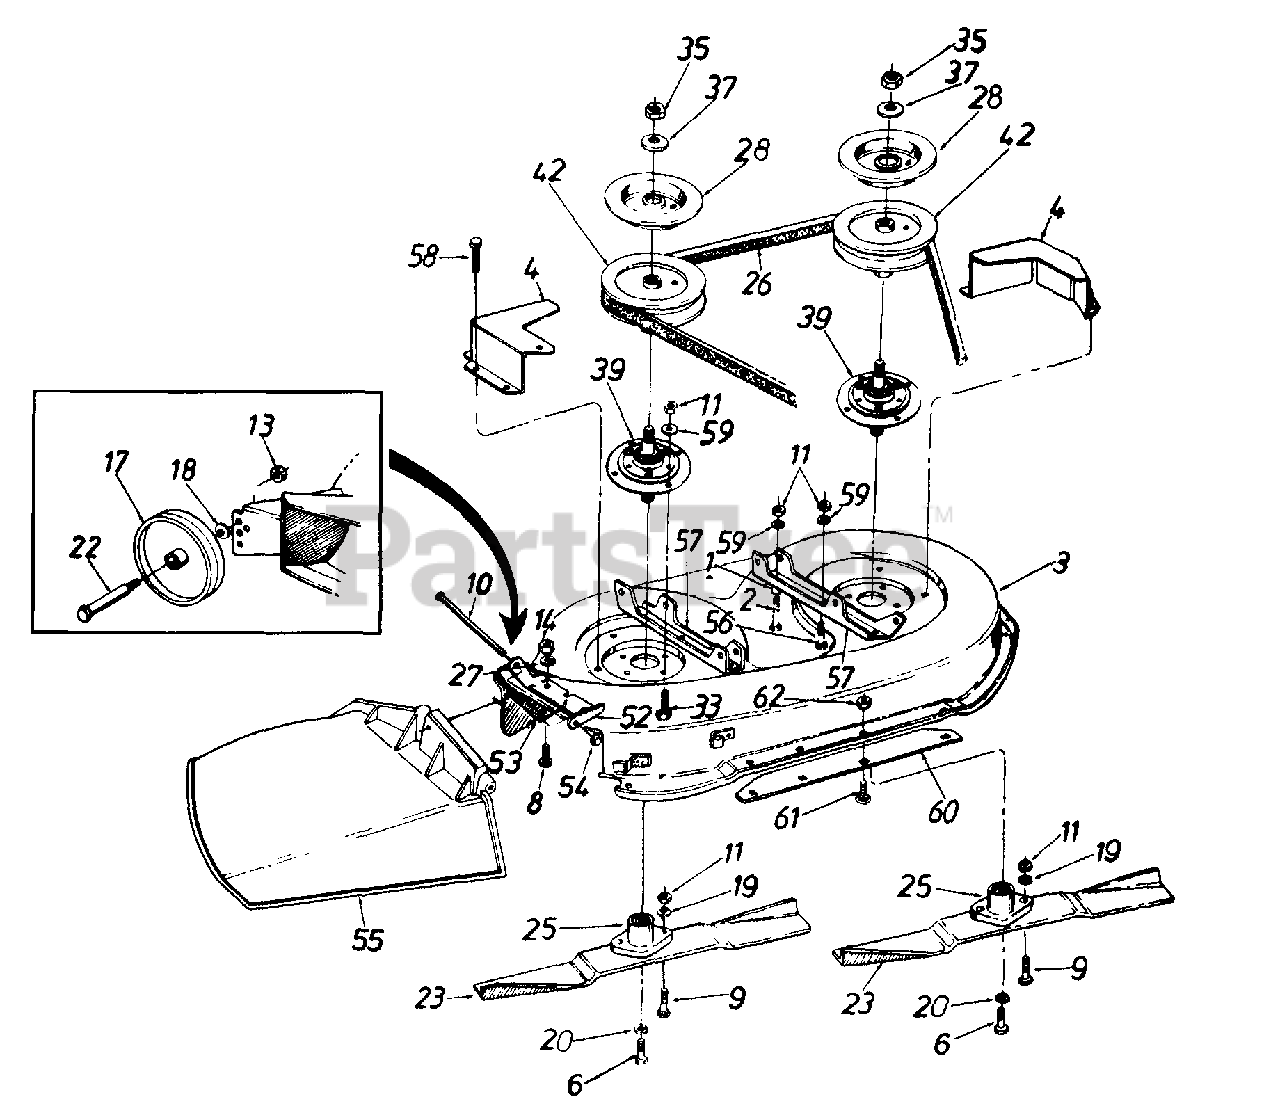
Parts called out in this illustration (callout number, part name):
1	Spacer .33" I.D. x .88"
2	Hex Bolt 5/16-24 x 1.25" Lg.
3	38" Deck Ass'y. w/Deck Wheels
6	Hex Bolt 3/8-24 x 1.0" Lg.
8	Hex Bolt 1/4-20 x .62"
9	Hex Bolt Special 5/16-24 x 1.0"
10	Hinge Pin
11	Hex Nut 5/16-24 Thd.
13	Hex Top L-Nut 3/8-16 Thd.
14	Hex Nut 1/4-20 Thd.
17	Deck Wheel - 5"
18	Bell-Wash. .40" I.D. x .88" O.D.
19	L-Wash. 5/16" I.D.
20	L-Wash. 3/8" I.D. - H.D.
22	Shld. Bolt .498" Dia. x 1.53"
23	High-Lift Blade
25	Blade Adapter
26	V-Belt
27	Bell-Wash. 1/4" I.D.
28	Brake Disc
33	Hex Bolt 5/16-24 x .75" Lg.
35	Hex Jam Nut 5/8-18 Thd.
37	L-Wash. 5/8" I.D.
39	Blade Spindle Ass'y. Comp.
42	5" Dia. Pulley
52	Hinge Mtg. Brkt.
53	Torsion Spring
54	Push Nut
55	Chute Ass'y. Comp.
56	Hex Bolt 5/16-24 x .75" Lg.
59	Bell-Wash. .345" I.D. x .88"
62	Hex Sems Nut 1/4-20 Thd.
